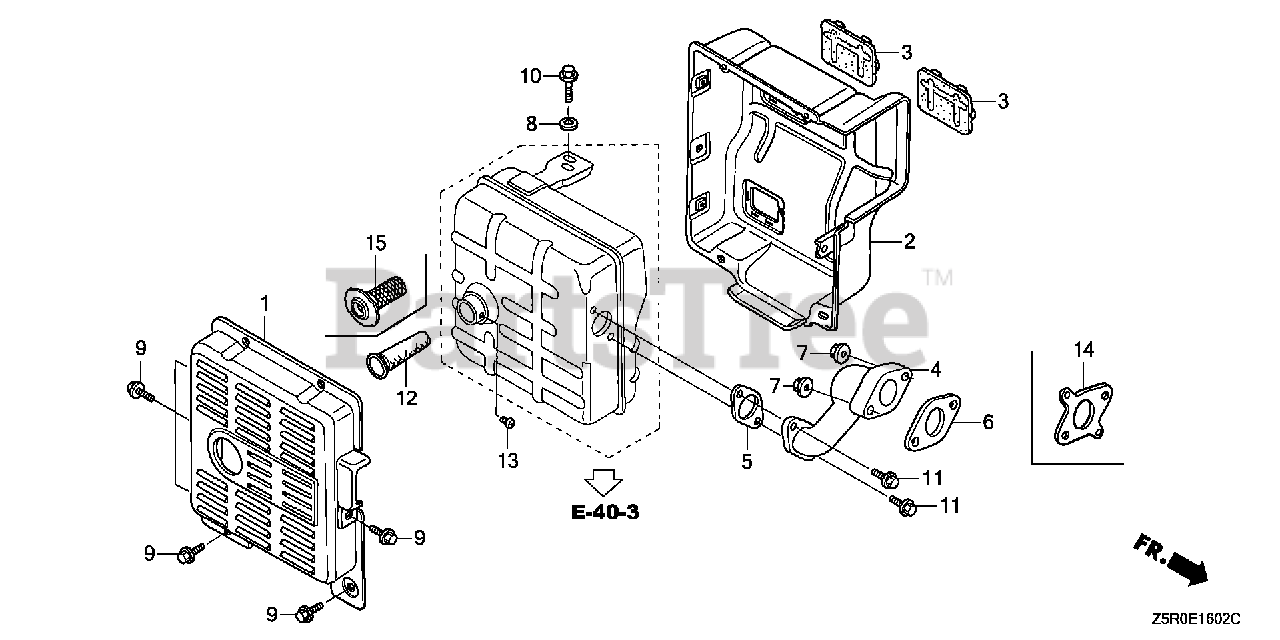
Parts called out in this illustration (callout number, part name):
6	GASKET, EX. PIPE
7	NUT, FLANGE (8MM)
12	ARRESTER, SPARK
13	SCREW, TAPPING (4X8)
14	GASKET, EX. PIPE
